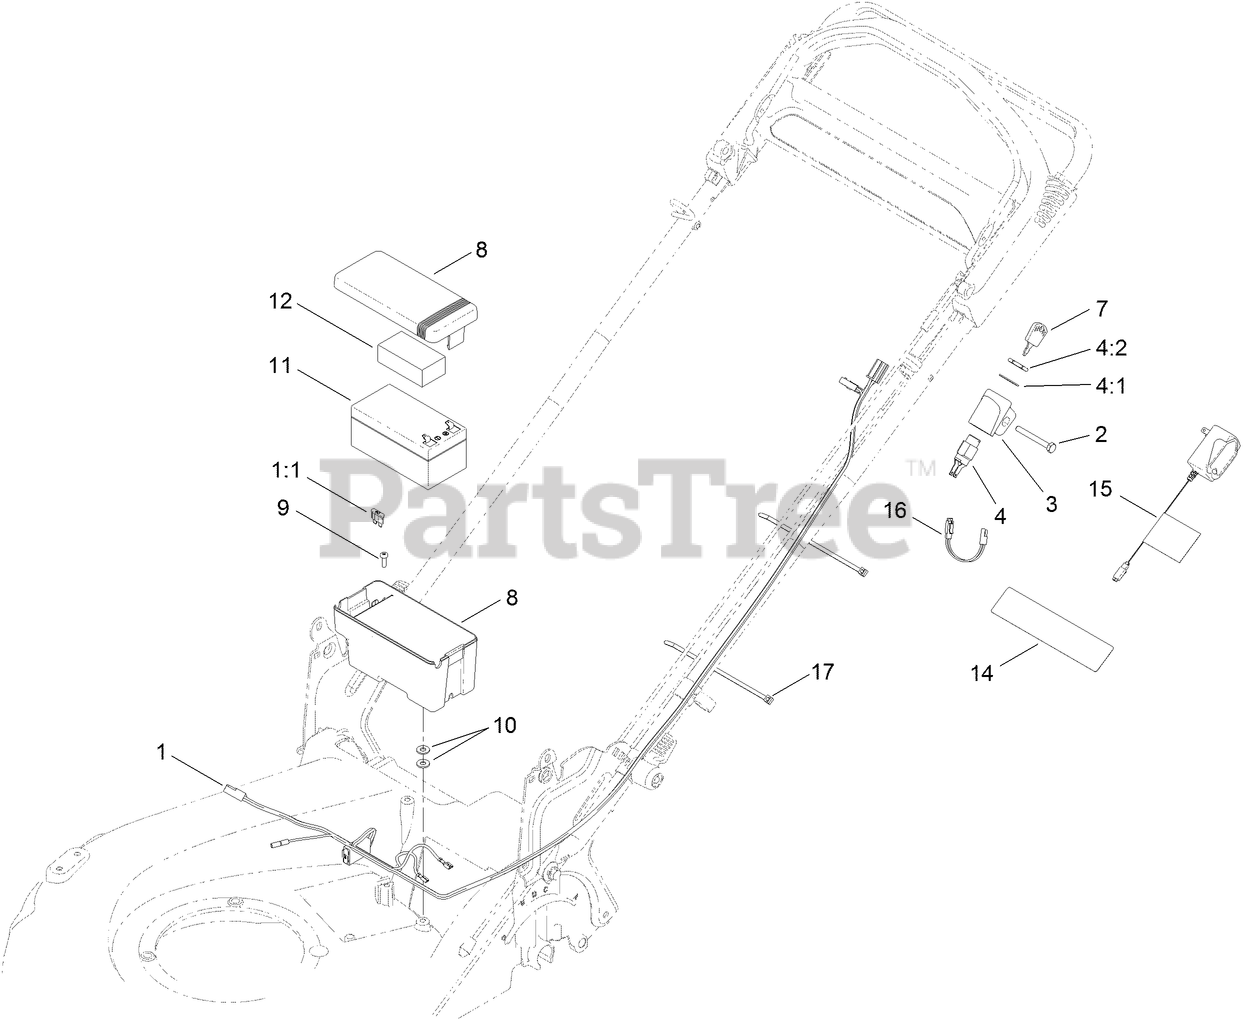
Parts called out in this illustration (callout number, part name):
1	HARNESS-WIRE
1:1	FUSE-40 AMP
2	SCREW-HH
3	MOUNT-SWITCH
4	STARTER SWITCH ASM
4:1	WASHER-LOCK
4:2	NUT-HH
8	BATTERY BOX ASM
10	WASHER-FLAT
11	BATTERY-WET
12	FOAM-BATTERY, TOP
14	DECAL-WARNING
15	CHARGER-EUROPEAN, 12V DC
16	ADAPTER-CHARGER
17	TIE-CABLE
